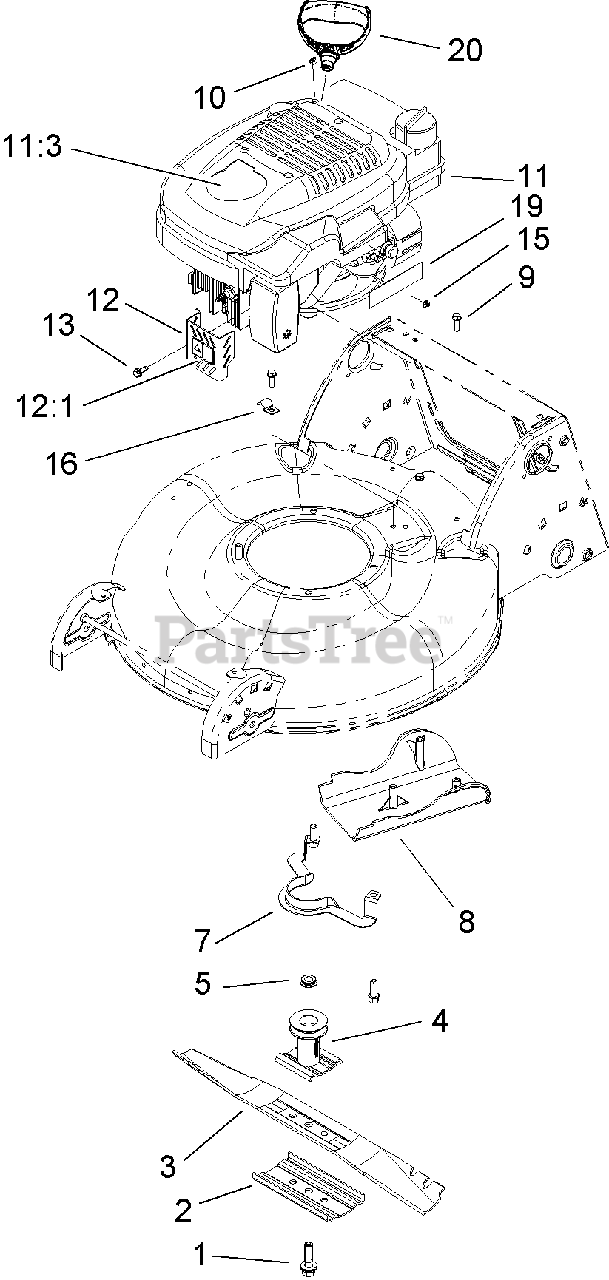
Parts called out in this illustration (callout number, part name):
1	BOLT-BLADE
2	SUPPORT-BLADE
3	BLADE-21 IN
4	BLADE DRIVER ASM
5	Spacer-Driver
8	COVER-BELT
9	SCREW-HWH
10	STOP-ROPE
11:3	DECAL-RECOIL
12	MUFFLER GUARD ASM
12:1	DECAL-SURFACE, HOT
13	SCREW-HWH
15	NUT-KEPS
16	CLIP-HALF
19	DECAL-PRIMER
20	HANDLE-RECOIL
